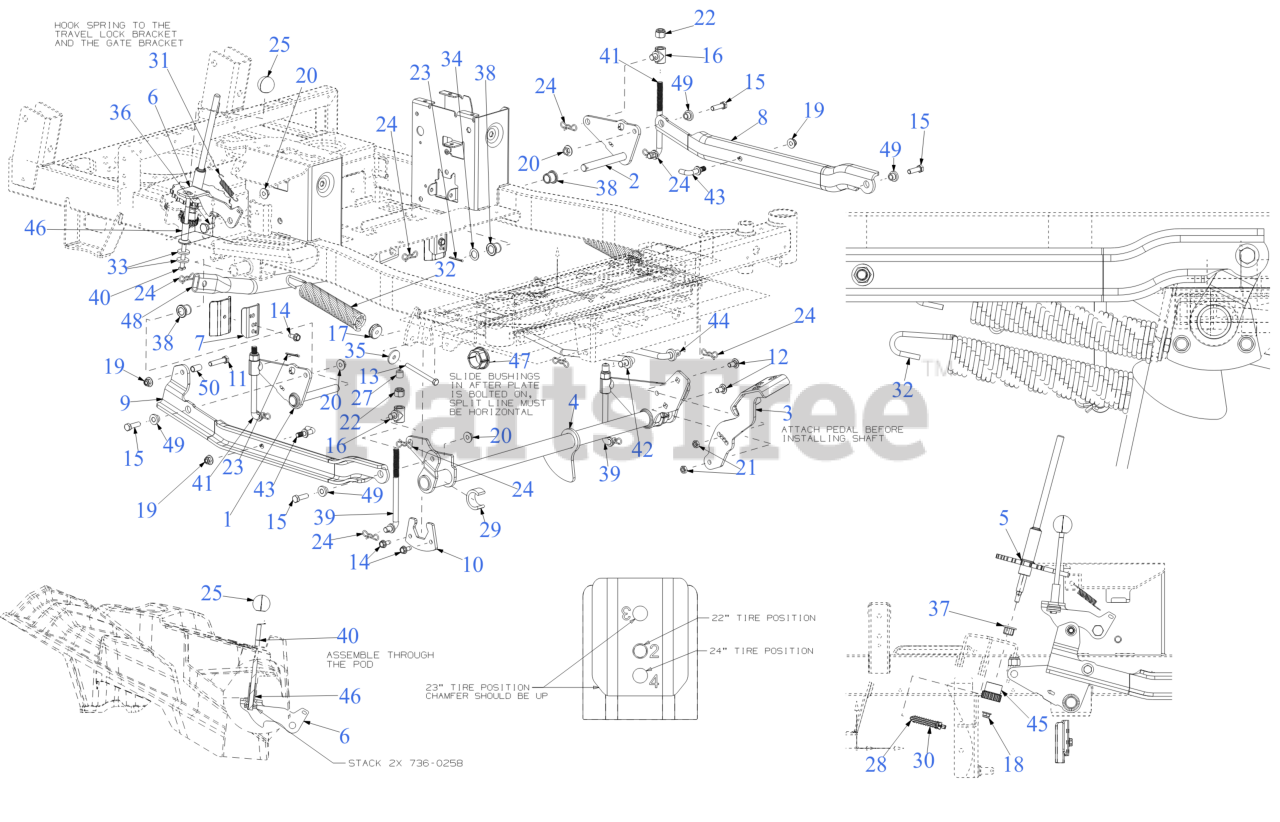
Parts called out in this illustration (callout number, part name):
1	BELLCRANK BRACKET (RH)
2	BELLCRANK BRACKET (LH)
3	DECK LIFT PEDAL
4	LIFT TUBE (FRONT)
5	DECK HEIGHT ADJUSTMENT ROD
6	TRAVEL LOCK PLATE
7	UPSTOP BRACKET
8	LIFT LINK (LH)
9	LIFT LINK (RH)
10	LIFT TUBE BRACKET
11	HEX SCREW 3/8-16 x 1.75 GR5
12	CARRIAGE BOLT 3/8-16 x .750 GR5
13	SCREW 5/16-18 x 3.50 GR5
14	SCREW 5/16-18 x .750
15	SCREW 3/8-16 x 1.25 GR5
16	LIFT ROD FERRULE
17	LIFT SPRING INSERT
18	FLANGE LOCK NUT 5/16-18
20	FLANGE LOCK NUT
21	HEX JAM NUT 3/8-16 GR5
22	HEX LOCK NUT NYLON
23	COTTER PIN
24	BOW TIE COTTER PIN
27	LIFT ROD END CAP
28	DETENT PLUNGER
29	LIFT TUBE SPACER
30	COMPRESSION SPRING .531 OD 1.75 LG
31	EXTENSION SPRING 2.675"
32	EXTENSION SPRING
33	FLAT WASHER .385 x 1.00 x .135
34	FLAT WASHER
35	WASHER-5/16 x 1.25X 1.27
36	SHOULDER SCREW
37	HEX FLANGE BEARING .506ID x .590LG
38	FLANGE BUSHING
39	DECK LIFT ROD 6.875"
40	TRAVEL LOCK ROD
41	DECK LIFT ROD 6.250"
42	DECK CONTROL ROD (RH)
43	LIFT SPRING MOUNTING ROD
44	DECK CONTROL ROD (LH)
45	DECK HEIGHT DETENT HUB
46	LOCK ROD SLEEVE SPACER
47	HEX FLANGE BEARING
48	DECK STABILIZER TUBE
49	SHOULDER SPACER 0.39x0.575x0.312
50	SPACER .380x.500x.875
